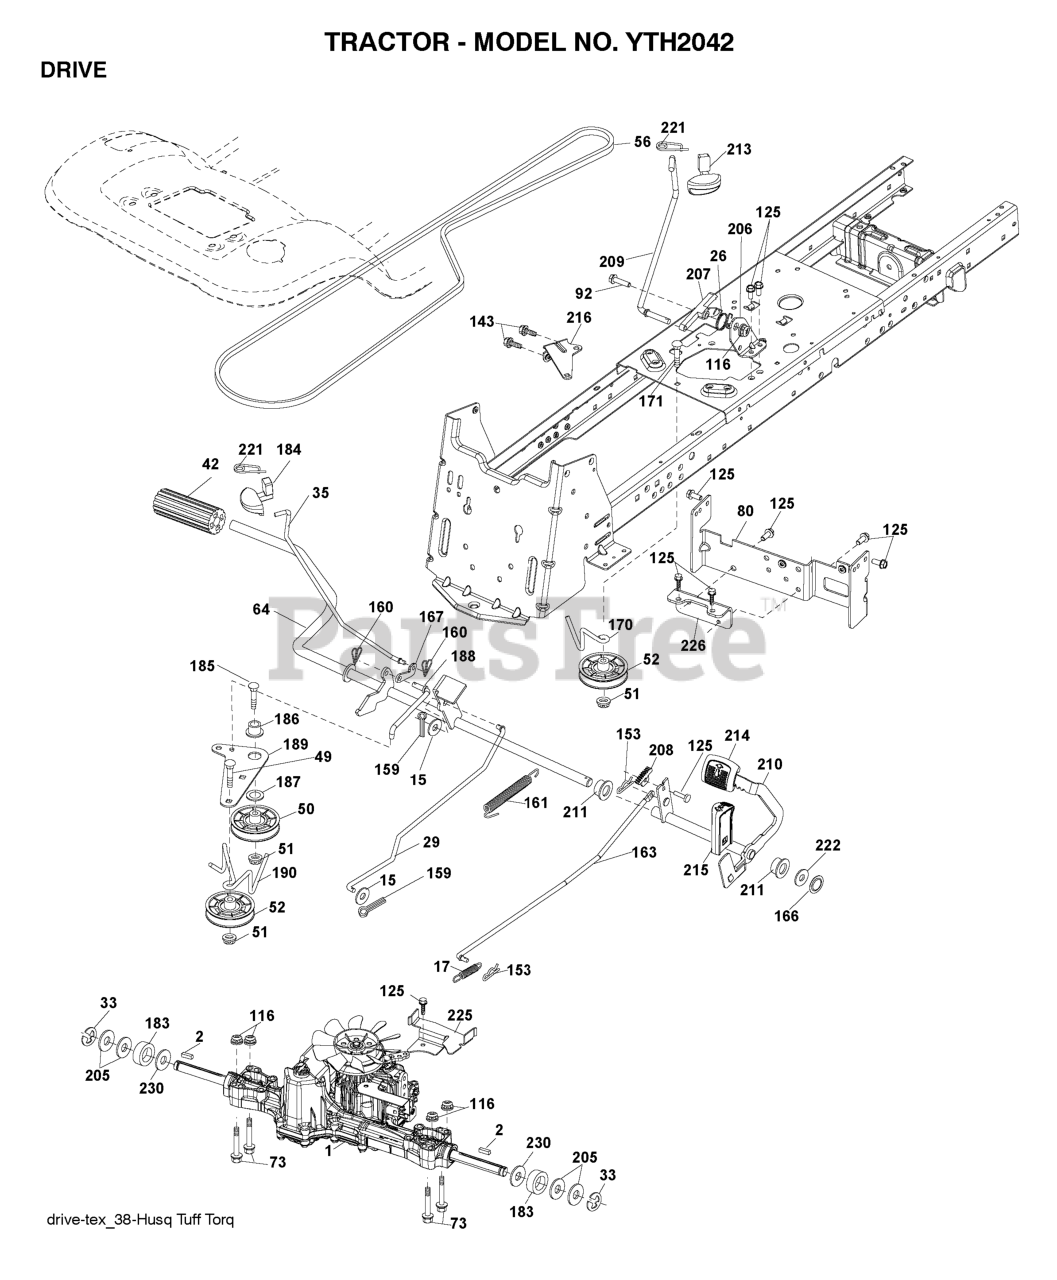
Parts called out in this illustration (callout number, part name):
1	TRANSAXLE, TUFFTORQ K46
2	SQUARE KEY
15	WASHER
17	SPRING.BRAKE.K46
26	SPRING.RETURN.CRUISE
29	ROD.BRAKE.K46
35	ROD.BRAKE.PARKING.GT.H
42	PEDAL COVER T
50	IDLER.FLAT.910.OFFSET
51	NUT LOCK FLG 3/8-16 UNC
52	IDLER.V-GROOVE.910.OFFSET
56	V-BELT.MOWER.92.40.42/K46
64	SHAFT.ASM.PEDAL.BRK.CNTR
80	STRAP TORQUE
92	BOLT
116	NUT LOCK HEX FLANGE 5/16-18
125	SCREW
143	Screw 5/16-18 x 1/2 Hex, Self Tapping 5/16-18 x 1/2
153	RETAINER M
159	COTTER PIN
160	RETAINER CLIP
161	SPRING.RETURN.CLUTCH.2006
163	ROD.CONTROL.PEDAL.K46
166	NUT.PUSH.625.2006
167	LATCH.BRAKE.SPRING
170	KEEPER.V-IDLER.CENTER.
183	SPACER AXLE
184	HANDLE.PARKG.BRK.HUSQ X667
186	SPACER.RETAINER
187	WASHER 12/32X2X10GA
188	RP.LINK.CLUTCH.GROUND.DRIVE
189	BELLCRANK.GROUND.DRIVE.TEX.
190	KEEPER.BELLCRANK.DRIVE
206	BRKT.MOUNT.LATCH.CRUIS
207	LATCH.CONTROL.CRUISE
208	GEAR.SECTOR.CONTROL.CR
209	ROD.CONTROL.CRUISE.GT.
210	ROCKER.ASM.PEDAL.CONTR
211	BEARING.NYLON
213	KNOB.CONTROL.CRUSIE.HU
214	PEDAL.FORWARD.TEX.GT.4
215	PEDAL.REVERSE.TEX.GT.4
216	BRACKET.PULLEY.IDLER.W/TEX
221	RETAINER.SPRING.CLIP.H
222	WASHER 21/32 X 1-1/4 X 10 GA.
225	KEEPER.BELT.TRANSAXLE.K46
226	BRACKET.MOUNT.TORQUE.K46.TLT
230	WASHER.HARDENED
